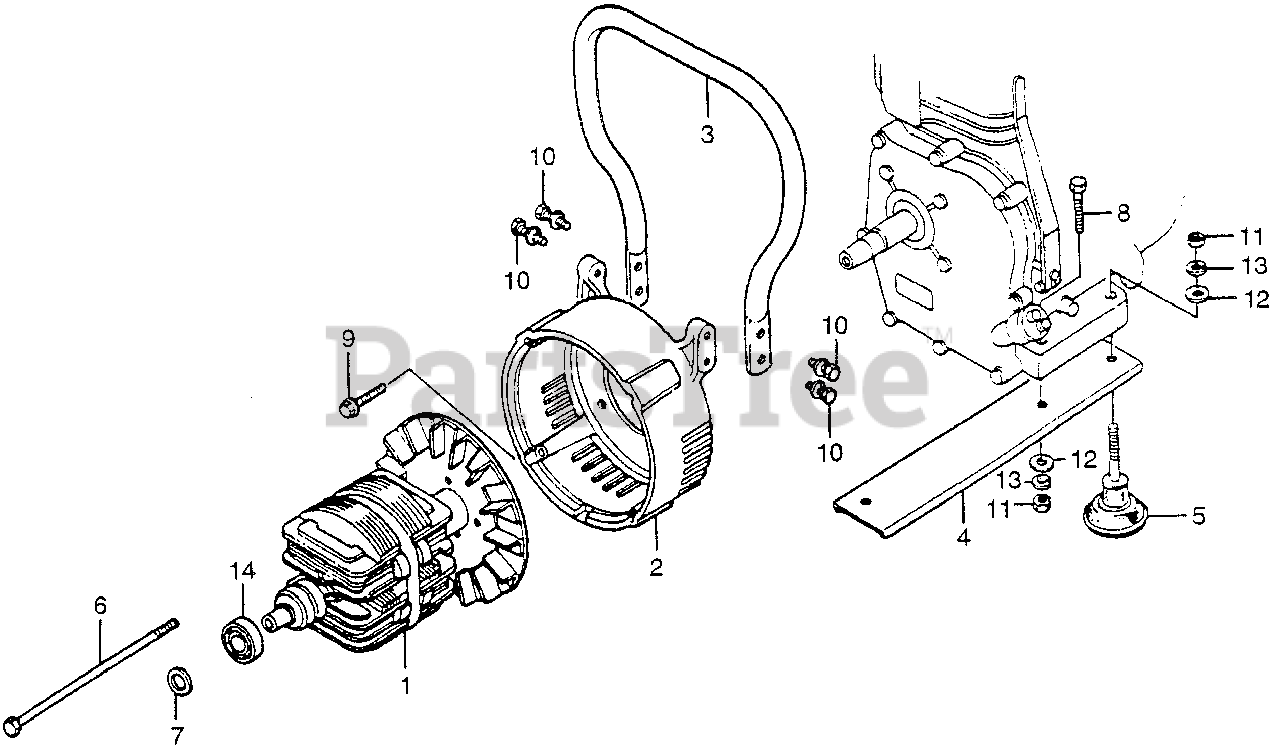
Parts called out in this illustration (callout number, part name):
1	ROTOR
2	HOUSING, FR. *R8* (BRIGHT RED)
3	HANDLE, CARRY (NOT AVAILABLE)
4	BED, FRAME
5	RUBBER (LOWER)
6	BOLT, HEX. (5/16X160)
7	WASHER (8MM)
8	BOLT, HEX. (8X36)
8	BOLT, HEX. (8X35)
9	BOLT-WASHER (8X25)
10	BOLT-WASHER (8X25) (NOT AVAILABLE)
11	NUT, HEX. (8MM)
12	WASHER, PLAIN (8MM)
13	WASHER, SPRING (8MM)
14	BEARING, RADIAL BALL (6203UU)
